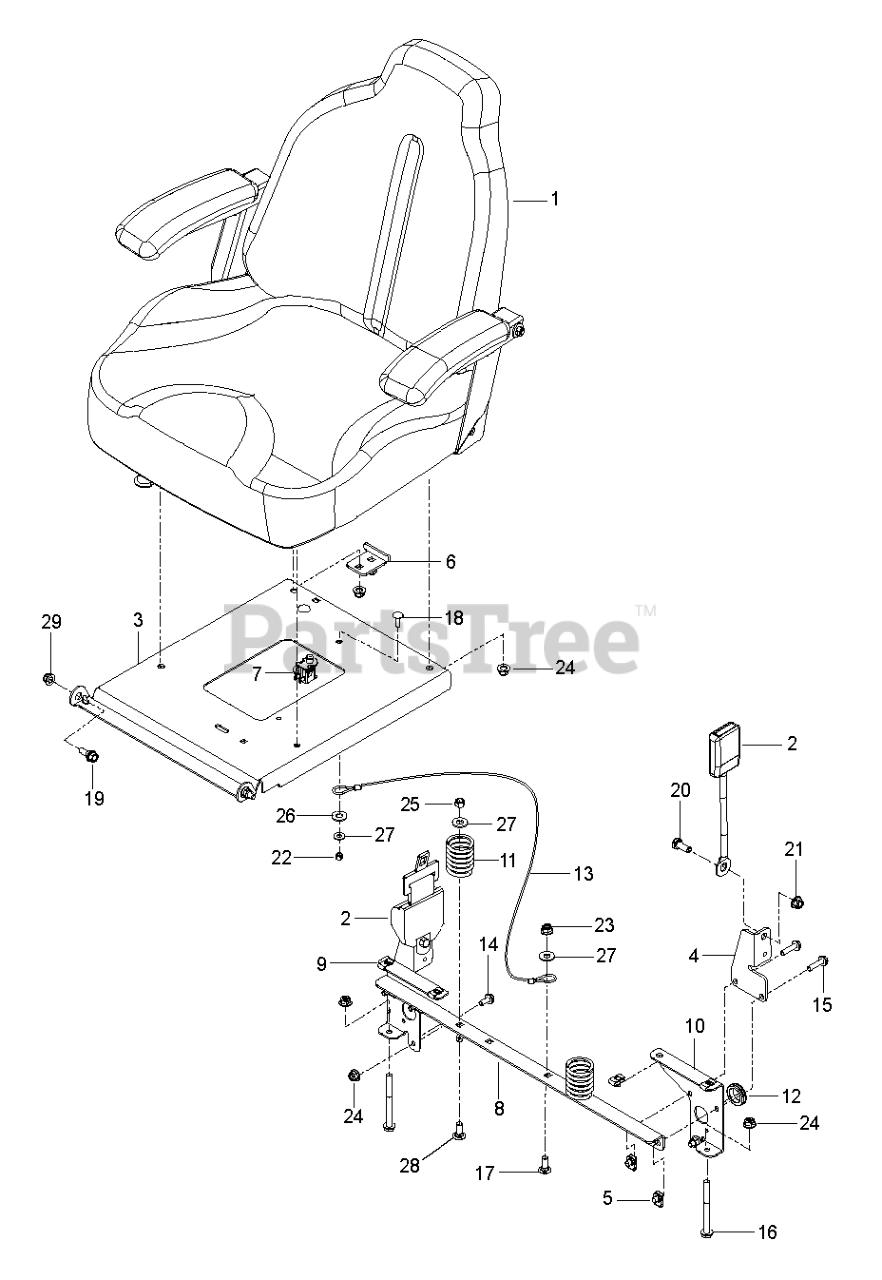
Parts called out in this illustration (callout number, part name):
1	SEAT.ASM.907.TRACK.W/O.BELT
2	SEAT BELT, RETRACTABLE
3	SUPPORT.SEAT.ORANGE
4	MOUNT.SEAT.BELT.BLACK
5	U-CLIP 5/16-18 NUT RETAINER
6	STOP, SEAT - BLACK
7	SWITCH.SNAPMOUNT.NC
8	SUPPORT.SEAT. BLK
9	SUPPORT.LT.BLK
10	SUPPORT.RT.BLK
11	SPRING.COMPRESSION.SEAT.BLACK
12	RUBBER GROMMET
13	SEAT LANYARD
14	HHFS 5/16-18 X 3/4
15	HHFS 5/16-18 X 1.25 TPBLT GD 5
16	BOLT.HEX.FLNG.5/16-18X3.75
17	RHSNB 3/8C X 1
18	1/4-20X3/4 CARR BLT
19	SB 5/16-18 HEX HD GD5, BLK ZN
20	SCREW 7/16-20 X 1 HHB GR5
21	NUT HEX 7/16F LOCK RP
22	NUT.1/4-20.HEX.NYLOC.ZD
23	NUT 3/8-16 HEX FLG NYLOC ZD
24	5/16-18 NYLOC FLANGE NUT
25	NUT 3/8-16 NYLOC
27	RP WASHER 3/8 FLAT
28	RHSNB 3/8C X 1
29	NUT.71038.31-18.HEX.NYLOCK
